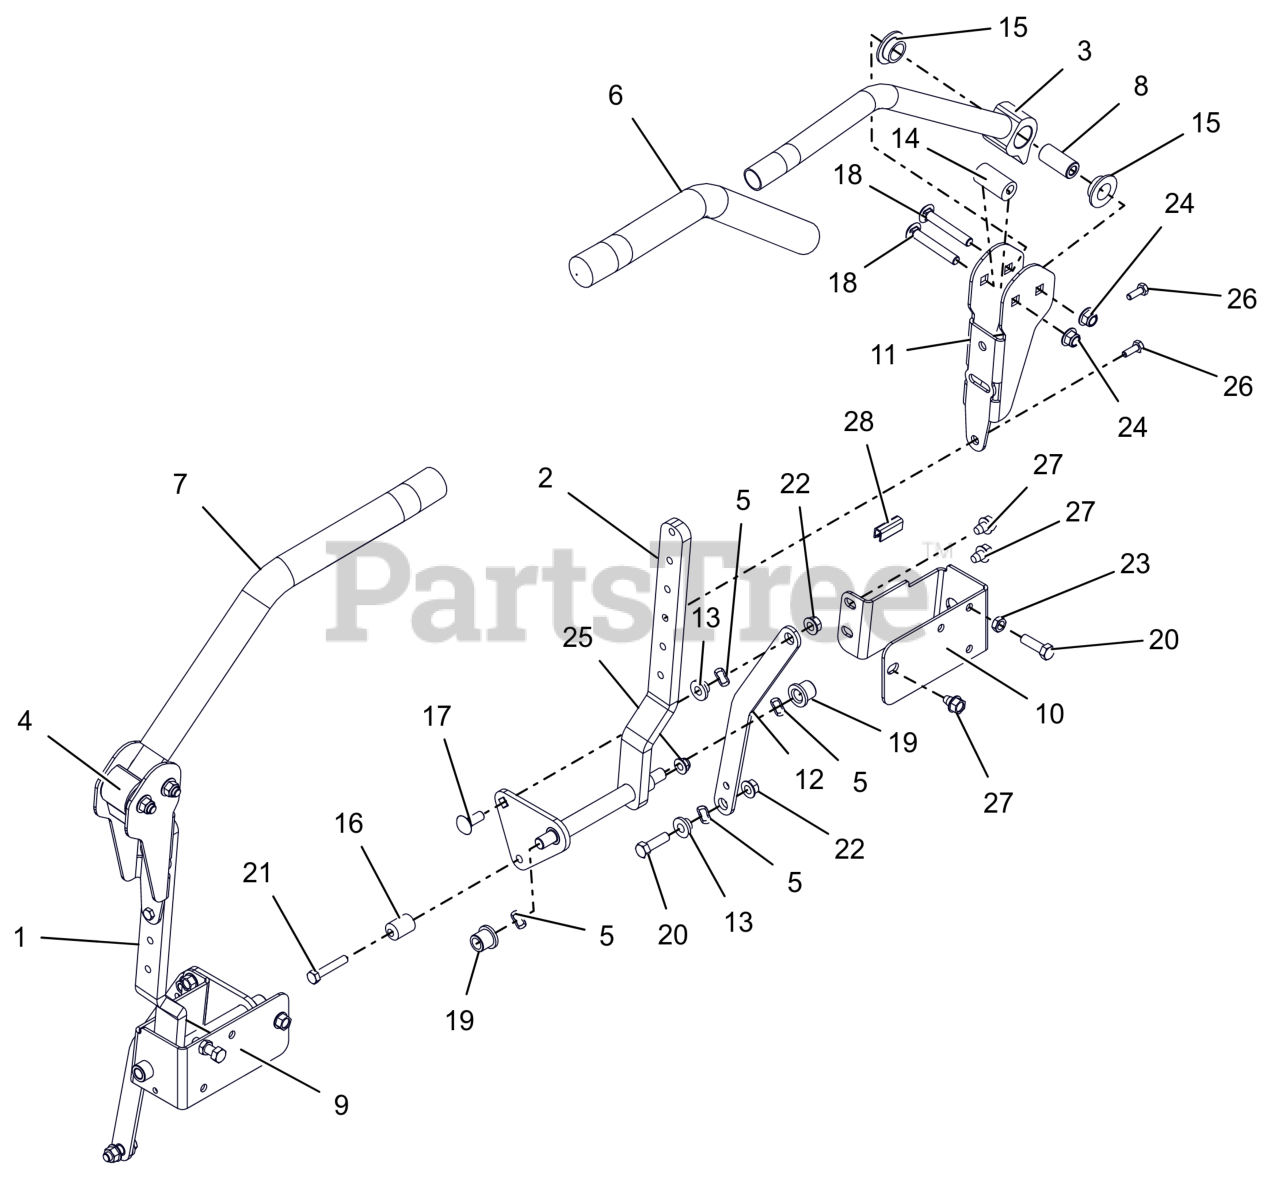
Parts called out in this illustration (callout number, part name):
1	WMT,PT/PT100RH LOWER CNTRL ARM
2	WMT,PT/PT100LH LOWER CNTRL ARM
3	WLDMT, CONTROL HANDLE-LH (BLACK)
4	WLDMT, CONTROL HANDLE-RH
5	WAVE WASHER .531X.781X.125FH
6	GRIP, HANDLEBAR
7	GRIP, HANDLEBAR
8	SPACER, STEERING ARM
9	RH PT/PT100 DRV CNTRL STOP-RED
10	LH PT/PT100 DRV CNTRL STOP-RED
11	ADJ UPPER CONTROL ARM BRKT-BLK
12	LINK, DRIVE CONTROL - BLACK
13	BSHG-FLG .385X.500X.875X.406
14	BSHG, ECCENTRIC.406X.875X1.625
15	BSHG-FLG .762X1.48X.44 NYL
16	ECCENTRIC
17	BLT, RHSN .38-16X1.00 G5 ZCC
18	BLT, RHSSN.38-16X2.50 G5 ZCC
19	BHSG-FLG .500X.750X.750X.125
20	BLT, HEX .38-16X1.25 G5 ZCC
21	BLT, HEX .31-18X1.75 G5 ZCC
22	NUT-LK-CTR-FLG .375-16 GF ZCC
23	NUT-JAM .375-16 G2 ZCC
24	NUT,NYL-FLG .38-16 GF ZCC
25	NUT,NYL-FLG .31-18 GF ZCC
26	BLT, HEX .25-20X.75 G5 ZCC
27	SCR,TAP .375-16X.50 HWH TR ZCC
28	STRIP, COWL
